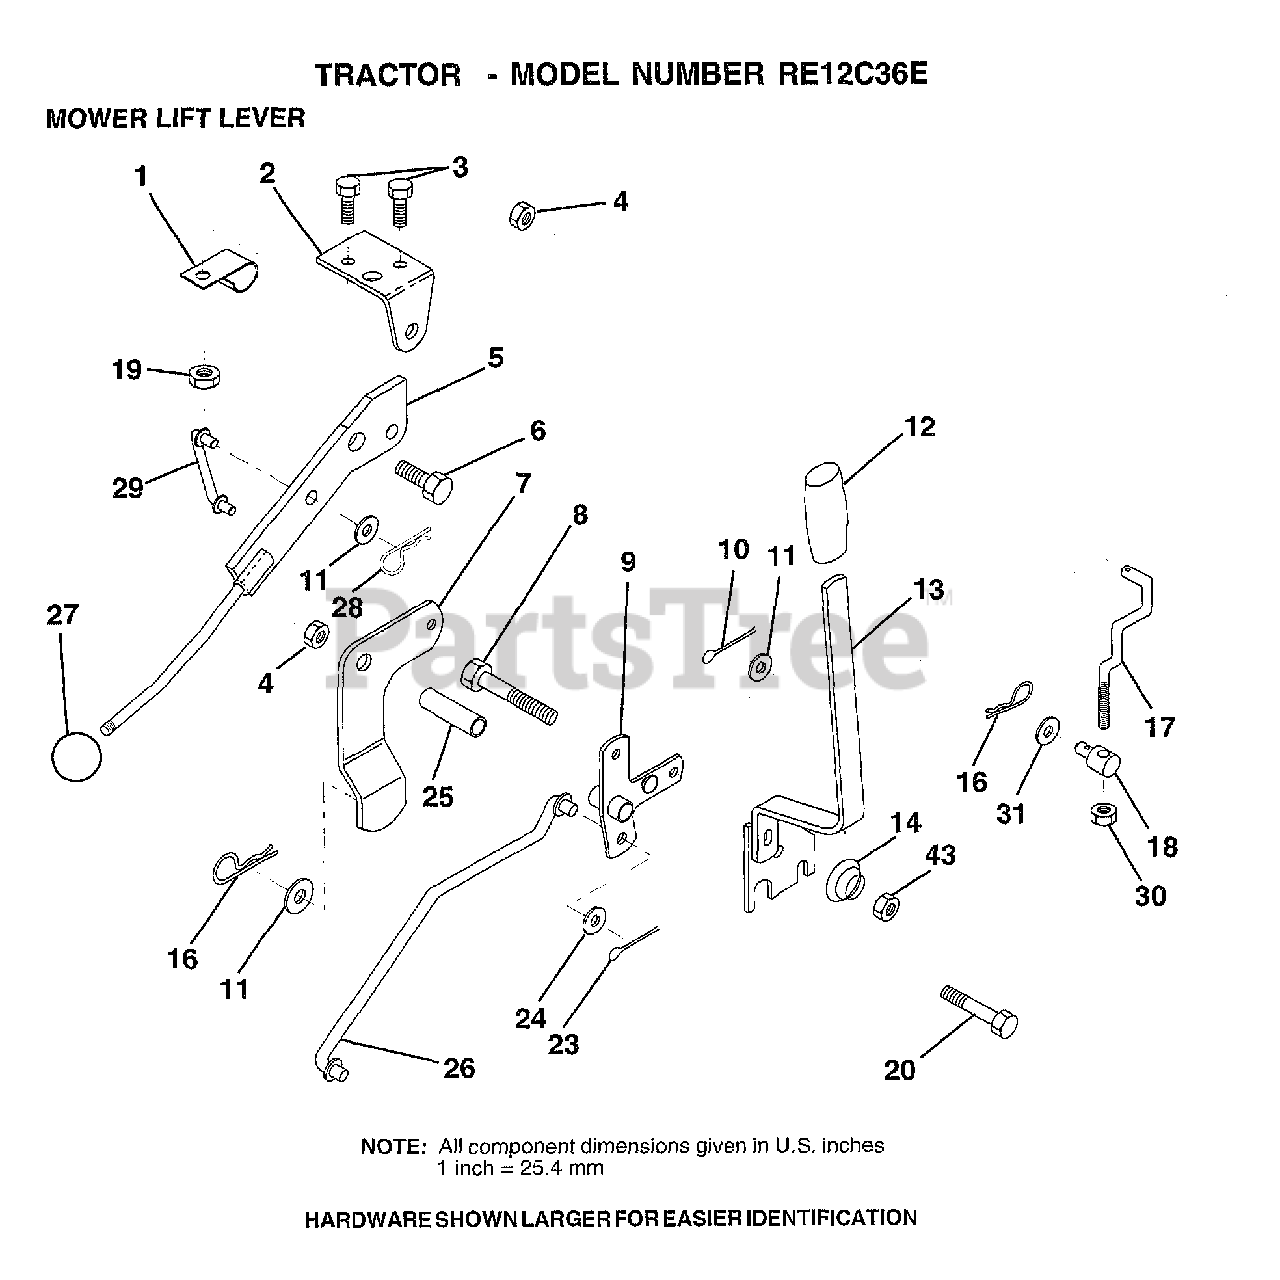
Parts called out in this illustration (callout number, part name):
1	"CLIP,INSULATOR"
2	BRKT CLUTCH
3	BOLT HXHD FIN
5	LEVER.ASM.CLUTCH
6	"BOLT, SHOULDER LT"
7	MWR CLUTCH ARM AS
8	BOLT
9	"BELLCRANK,LIFT"
10	COTTER PIN
11	WASHER
13	HANDLE.ASM.LIFT
14	SPRING COMPRESSIO
16	SPRING.RETAINER
17	"LINK,LIFT FRT"
18	TRUNION ADJ
20	BOLT
23	PIN COTTER 1/8
25	TUBE SPACER
26	ROD LIFT MOWER
27	KNOB T(3/8 HOLE)
28	RETAINER M
29	CLUTCH LINK
30	NUT
31	WASHER
